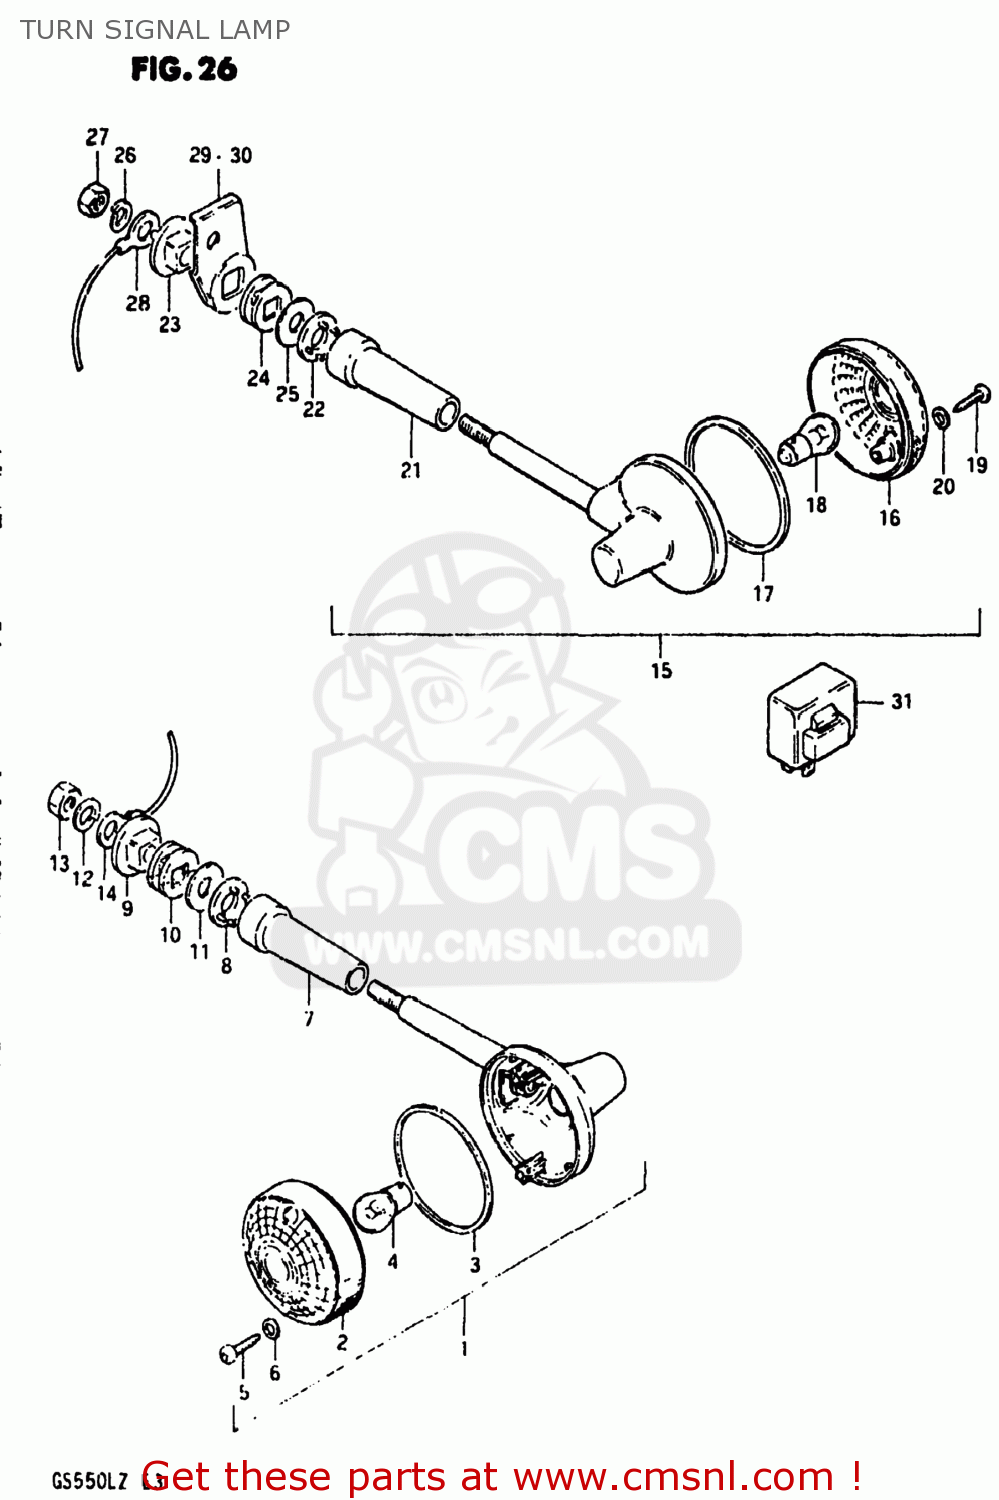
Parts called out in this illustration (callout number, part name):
1	LAMP ASSEMBLY,REAR TURN SIGNAL
2	LENS
3	GASKET (NAS)
4	BULB(12V23W,STANLEY,A4577A)
5	SCREW
6	GASKET (NAS)
7	COVER,STAY
8	SPACER
9	SPACER
10	CUSHION
11	WASHER (10.5X30X2.3)
12	LOCK WASHER
13	NUT
14	WIRE
15	LAMP ASSEMBLY,REAR TURN SIGNAL
16	LENS
17	GASKET (NAS)
18	BULB(12V23W,STANLEY,A4577A)
19	SCREW
20	GASKET (NAS)
21	COVER,STAY
22	SPACER
23	SPACER
24	CUSHION
25	WASHER (10.5X30X2.3)
26	LOCK WASHER
27	NUT
28	WIRE
29	BRACKET,REAR TURN SIGNAL
30	BRACKET,REAR TURN SIGNAL
31	RELAY,TURN SIGNAL
